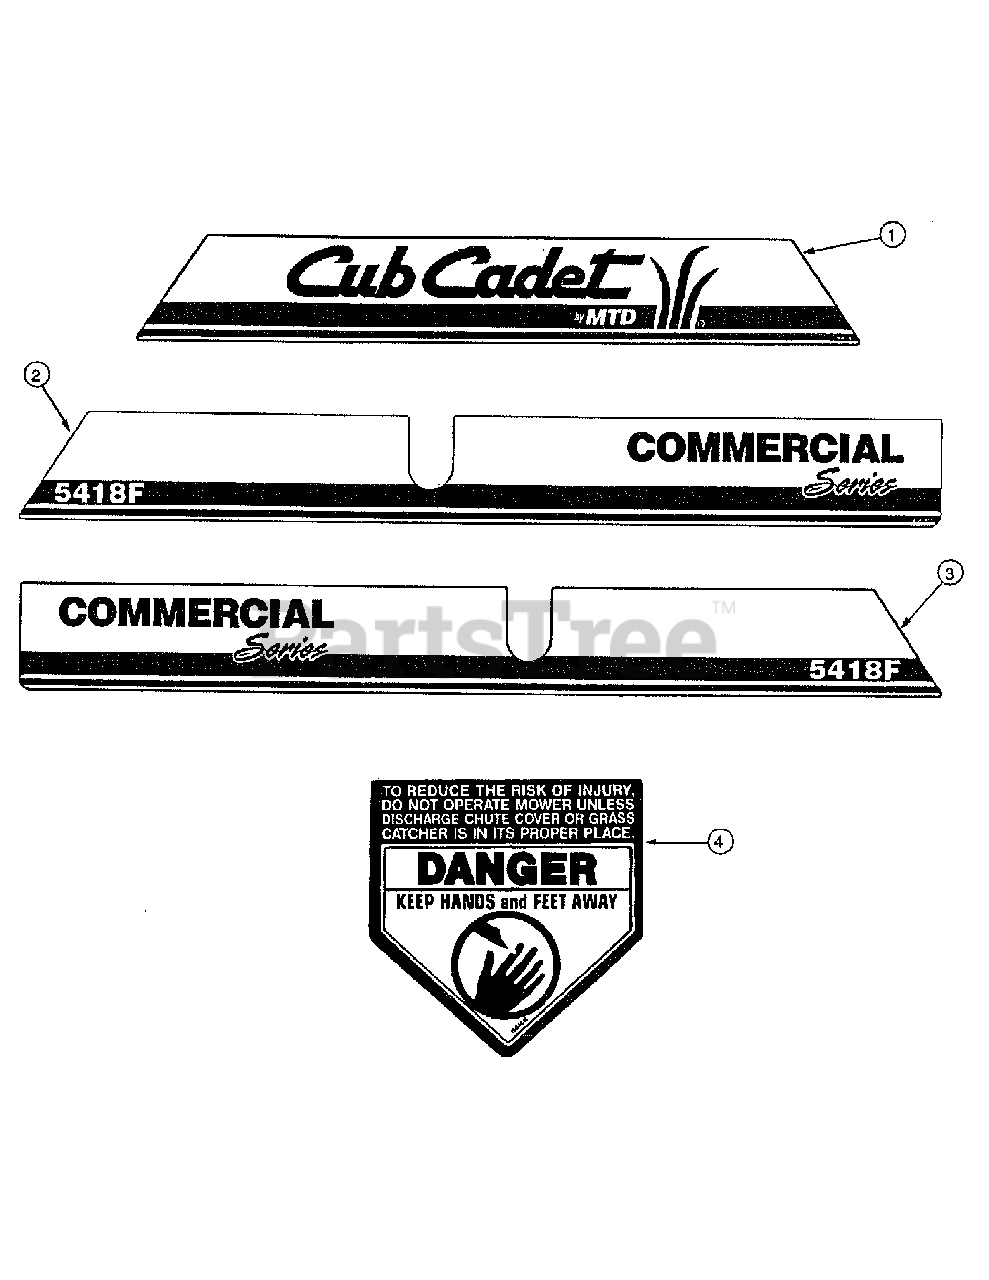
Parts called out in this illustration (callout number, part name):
1	Graphic, Belt Cover Front
2	Graphic, 5418F, Belt Cover Left
3	Graphic, 5418F, Belt Cover Right
4	Graphic, Danger Cut Finger
